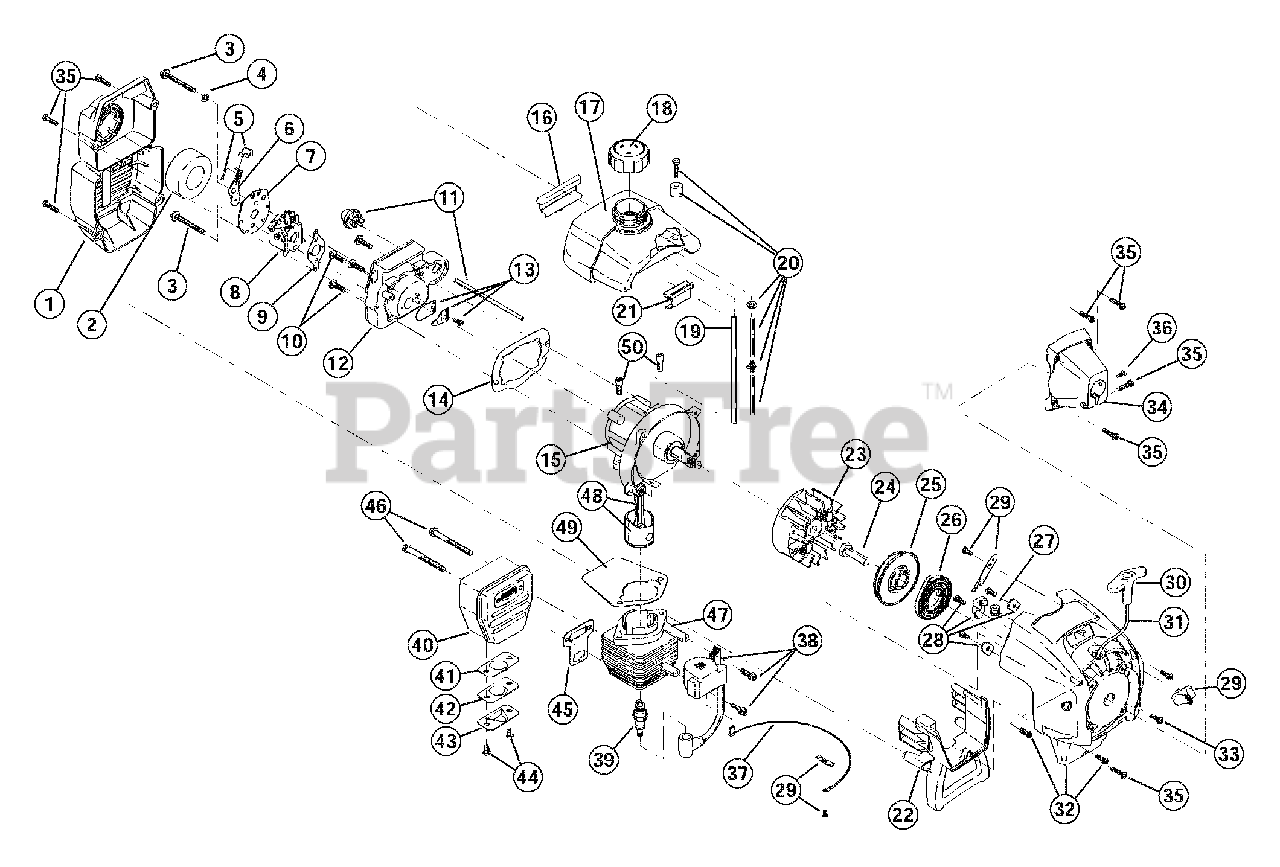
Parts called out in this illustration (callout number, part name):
1	Air Cleaner/Muffler Cover Assembly
2	Air Cleaner Filter
3	Carburetor Mounting Screw Assembly
4	Wavey Washer
5	Choke Knob and Screw
6	Choke Lever Assembly
7	Choke Lever and Plate
8	Carburetor Assembly
9	Carburetor Gasket
10	Carb Mount Screw
11	Primer and Hose Assembly
12	Carb Mount Assembly
13	Reed Assembly
14	Carburetor Mount Gasket
15	Crank Case Service Assembly
16	Rear Mounting Pad
17	Fuel Tank Assembly
18	Fuel Cap Assembly
19	Fuel Return Line
20	Fuel Line Assembly
21	Front Mounting Pad
22	Shroud Extension and Stand
23	Flywheel Assembly
25	Recoil Pulley Assembly
26	Recoil Spring
27	Rope Guide
28	Pulley Retainer Assembly
29	Switch Assembly
30	Pull Handle
32	Starter Housing Assembly
33	Housing Screw
34	Clutch Cover Assembly
35	Cover Screw
36	Anti-Rotation Screw
37	Wire Lead
38	Module Assembly
39	Spark Plug
40	Muffler Assembly
41	Spark Arrestor Screen
42	Spark Arrestor Plate
43	Spark Arrestor Hood
44	Spark Arrestor Screws
45	Exhaust Gasket
46	Muffler Mounting Bolt
47	Cylinder Assembly
48	Piston and Rod Assembly
49	Cylinder Gasket
50	Cylinder Bolt
